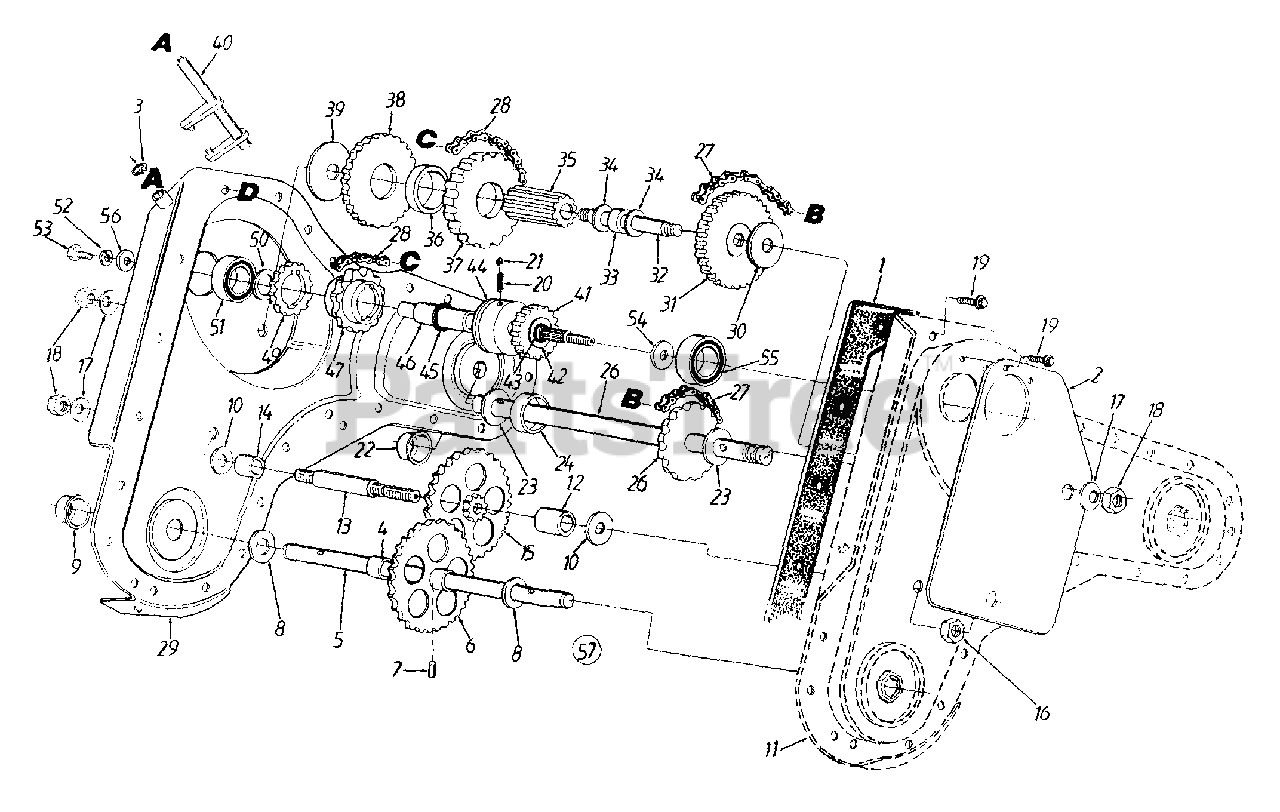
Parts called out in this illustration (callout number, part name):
1	Chain Case Gasket
4	Spacer .735" I.D. x .886" O.D.
5	Wheel Shaft
6	Spur Gear 46T
7	Pin Type "E" Grooved
8	Fl-Wash. .76" I.D. x 1.5" O.D.
9	Dust Cover Ass'y. .75" Shaft
10	Fl-Wash. 7/16" I.D. x 1-3/8" O.D.
13	Jack Shaft 2.06" Lg.
14	Spacer .635" I.D. x 1" O.D. x .37" Thk.
15	Gear Idler Ass'y.
16	Hex Patch L-Nut 7/16-20 Thd.
17	Bell-Wash. .45" I.D. x 1" O.D.
18	Hex Nut 7/16-20 Thd.
19	Hex Wash. Hd. TT-Tap Scr. 1/4-20 x .5" Lg.
20	Spring Detent
22	Dust Cover Ass'y. 1" Shaft
23	Thrust Wash. 1.03" I.D. x 1.62"
24	Spacer 1" I.D. x 2" O.D. x .5" Thk.
26	Tine Shaft Ass'y.
27	Chain - #50 5/8" Pitch x 52 Links - Endless
28	Chain - #41 1/2" Pitch x 30 Links - Endless
30	Fl-Wash. 7/16" I.D. x 1-3/8" O.D.
31	Gear and Sprocket Ass'y.
32	Jack Shaft 5" Lg.
33	Spacer .636" I.D. x .86" O D.
34	Fl-Wash. .63" I.D. x .94" O.D.
35	Spur Gear 10T
36	Spacer 1.5" I.D. x 1.76" O.D.
37	Sprocket - #41 Chain
38	Reverse Gear 46T
39	Thrust Wash. .445" I.D. x 1.92"
40	Shifter Ass'y.
41	Spur Gear 17T
42	Fl-Wash. .69" I.D. x 1.06" O.D.
43	Retaining Ring .669" Shaft
44	Clutch Collar
45	Retaining Ring .875" Shaft
46	Drive Shaft
47	Sprocket 11T
49	Spur Gear 16T
50	Fl-Wash. 5/8" I.D. x 1" O.D.
51	Ball Bearing .669" I.D.
52	L-Wash. 1/4" I.D.
53	Hex Bolt 1/4-20 x .62" Lg.
54	Fl-Wash. .635" I.D. x 1" O.D.
55	Ball Bearing
56	Fl-Wash. .281" I.D. x .875" O.D.
57	Gear Case Ass'y. Comp.
